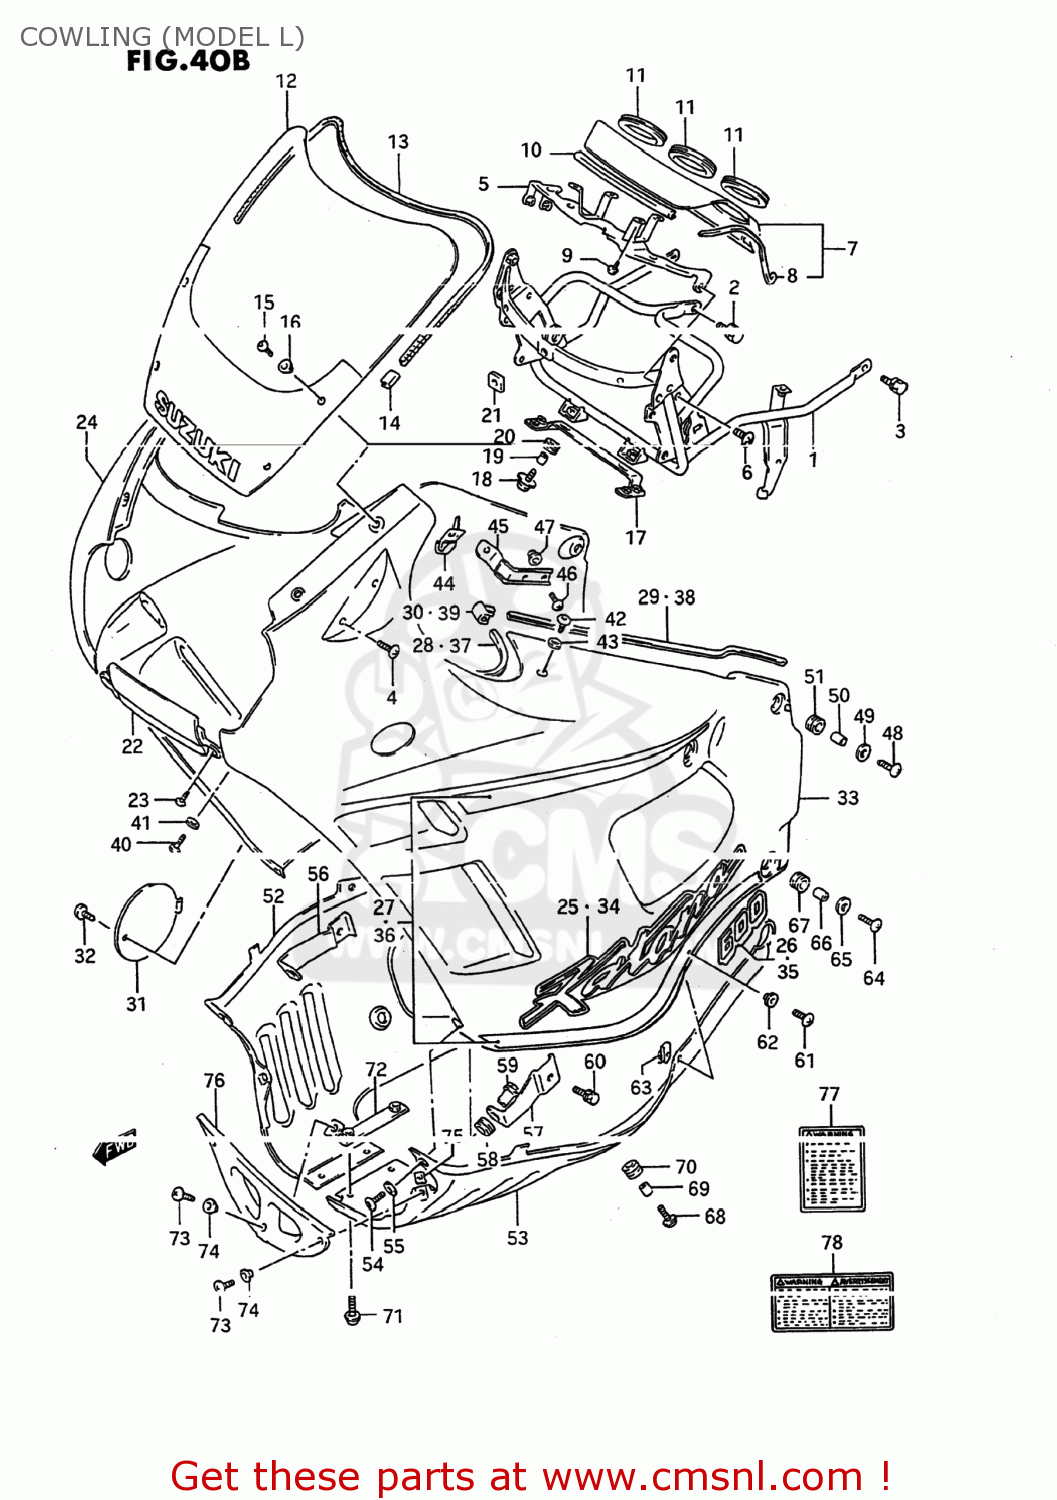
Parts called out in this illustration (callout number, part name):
1	BRACE,COWLING
2	BOLT
3	BOLT 6X12
4	SCREW 6X12
5	PLATE,METER FITING
6	SCREW 6X12
7	COVER,METER
8	MOLDING
9	SCREW 5X8
10	MOLDING,METER COVER
11	CUSHION,METER COVER
12	WINDOW,COWLING
13	MOLDING
14	CAP,MOLDING END
15	SCREW
16	WASHER(5.2X11X1)
17	PLATE,COWL CTR PANEL
18	SCREW(6X20)
19	SPACER (6,8X10X9.4)
20	CUSHION
21	CUSHION,SCREEN
22	PANEL,COWLING CTR
23	SCREW
24	COVER ASSEMBLY,COWLING,RIGHT (R
25	EMBLEM,COWLING (KATANA)
26	EMBLEM (600)
27	TAPE SET,COWLING STRIPE
28	MOLDING
29	MOLDING
30	JOINT,MOLDING END
31	LID,OIL
32	SCREW(6X16)
33	COVER ASSEMBLY,COWLING,LEFT
34	EMBLEM,COWLING (KATANA)
35	EMBLEM (600)
36	TAPE SET,COWLING STRIPE
37	MOLDING
38	MOLDING
39	JOINT,MOLDING END
40	SCREW(6X25)
41	WASHER(6.5X18X1.5)
42	SCREW(6X16)
43	WASHER(6.3X16X1.5)
44	BRACKET,COWLING UPR,R
45	BRACKET,COWLING UPR,L
46	SCREW(6X25)
47	NUT,COWLING SIDE BRKT
48	SCREW(6X25)
49	WASHER(6.5X18X1.5)
50	SPACER (6.1X9X9)
51	CUSHION
52	COVER,COWLING UNDER,R
53	COVER,COWLING UNDER,L
54	SCREW(6X30)
55	WASHER(6.5X18X1.5)
56	BRACKET,COWLING LWR,R
57	BRACKET,COWLING LWR,L
58	CUSHION
59	NUT,COWLING,FR
60	BOLT
61	SCREW(5X14)
62	WASHER(5.2X14X1.5)
63	NUT,HEADLAMP HOUSING,UPPER
64	SCREW(6X25)
65	WASHER(6.5X18X1.5)
66	SPACER(6.1X9X12.3)
67	CUSHION
68	SCREW(6X20)
69	SPACER (6.1X9X9)
70	CUSHION
71	SCREW, LOWER
72	BRACKET,FR UNDER COWL
73	SCREW
74	WASHER(5.2X14X1.5)
75	NUT,HEADLAMP HOUSING,UPPER
76	COVER,COWLING UNDER FR
77	LABEL (WARNING SCREEN)
78	LABEL,GENERAL WARNING
